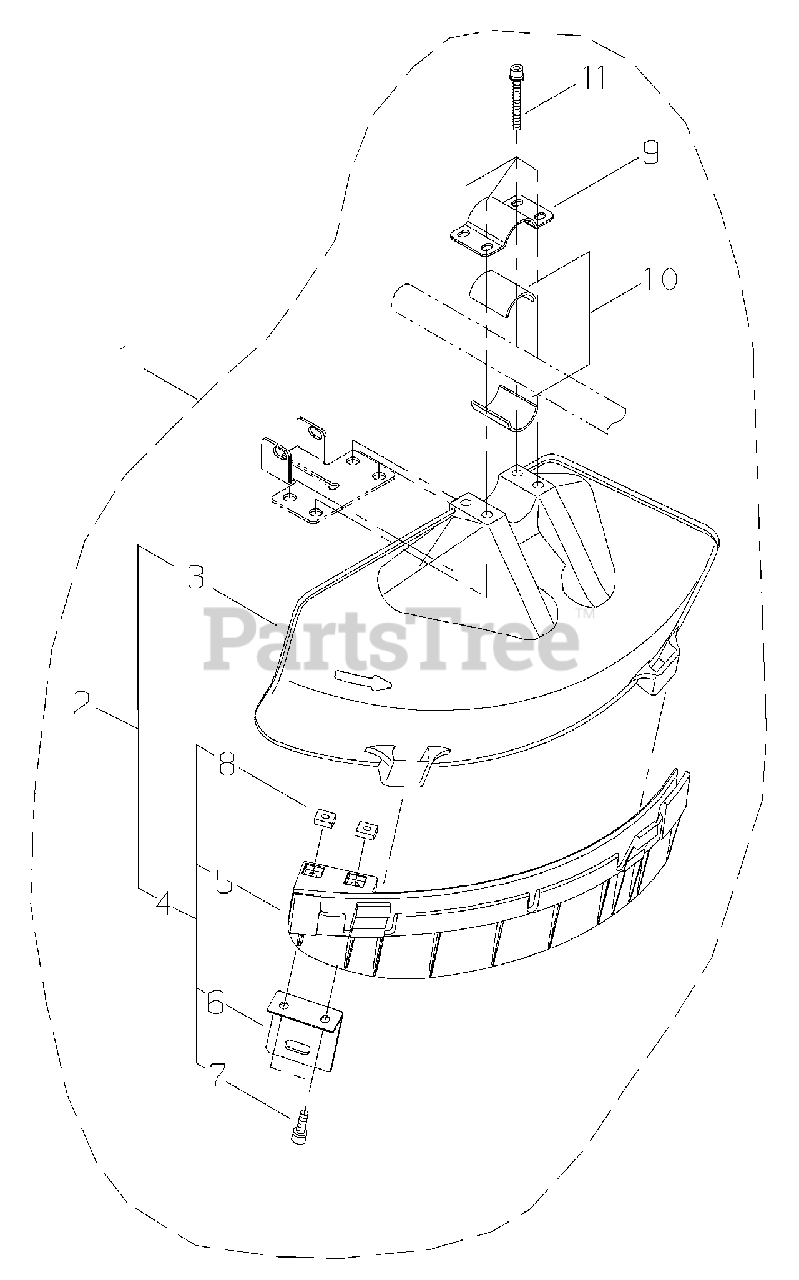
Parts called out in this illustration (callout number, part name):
1	GUARD SET
2	DEBRIS SHIELD KIT
3	SHIELD, DEBRIS
4	SHIELD GUARD KIT
5	SUBGUARD
6	CUTTER
7	BOLT M5×22
8	NUT M5
9	CLAMP, UPPER
10	SPACER 26
11	BOLT M5×45
